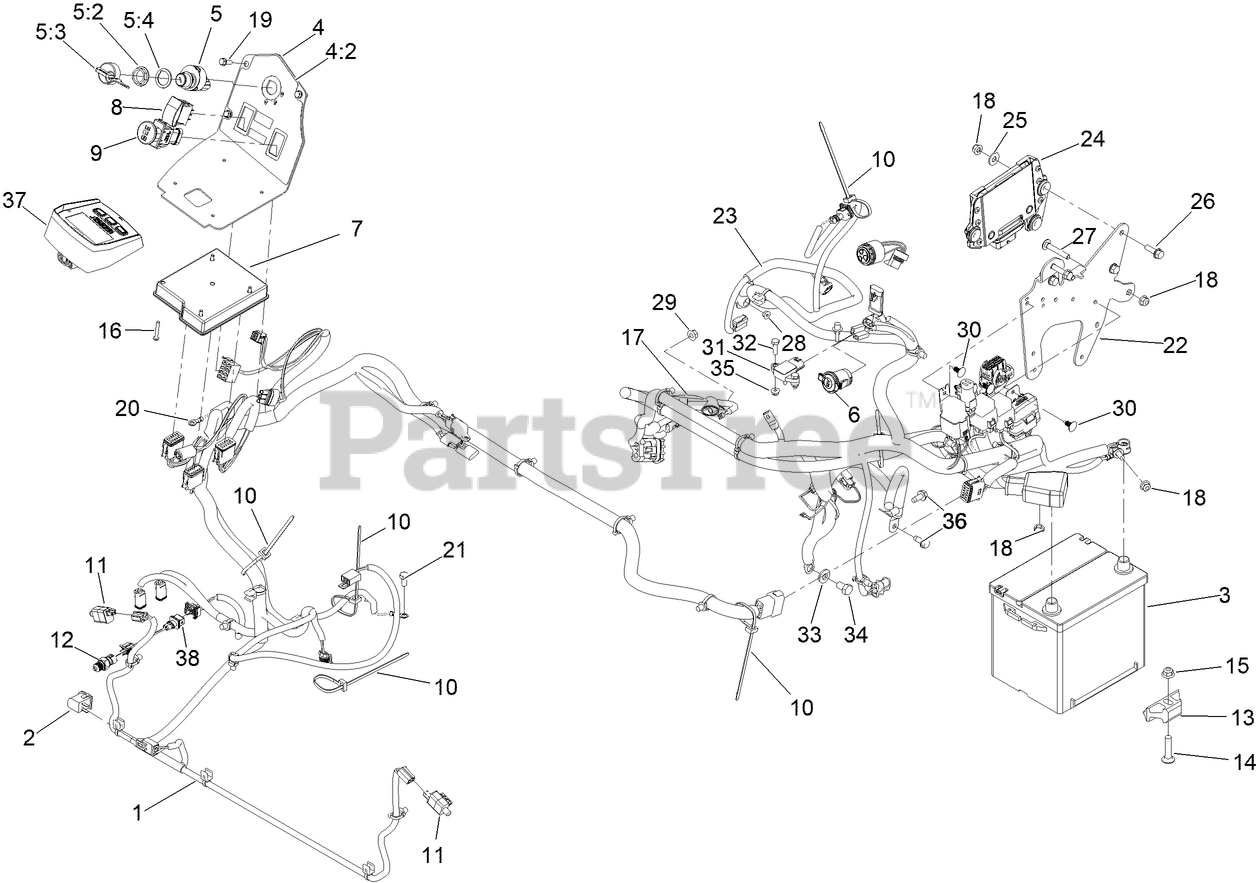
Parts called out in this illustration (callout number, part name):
1	HARNESS-WIRE
2	SWITCH-BAIL
3	BATTERY-DRY
4	CONSOLE ASM
4:2	DECAL-CONTROL PANEL
5	IGNITION SWITCH ASM
5:2	NUT-MOUNTING
5:3	IGNITION KEY SET
5:4	WASHER-BACKUP
6	PORT-POWER, 12V
7	MODULE-MCU
8	SWITCH
9	SWITCH-PTO, SEALED
10	TIE-CABLE
11	SWITCH
12	SENSOR-TEMPERATURE
13	RETAINER-BATTERY
14	SCREW-CARR
15	NUT-HF, NI
16	SCREW-PPH
17	CABLE-BATTERY
18	NUT-HF, NI
19	SCREW-HWH
20	HARNESS-WIRE, JUMPER
21	BOLT
22	BRACKET-MOUNT, ECU
23	HARNESS-WIRE, YANMAR
24	ECU ASM-SERVICE
25	WASHER-FLAT
26	SCREW-HHF
27	BOLT-CARR
28	NUT-HF
29	NUT-HF
30	PLUG-PLASTIC
31	SENSOR-ATM
32	SCREW-HH
33	WASHER-BELLEVILLE
34	SCREW-HH
35	NUT-HF
36	SCREW-HWHTF
37	MODULE-HORIZON
38	HARNESS-JUMPER TEMP SENSE
